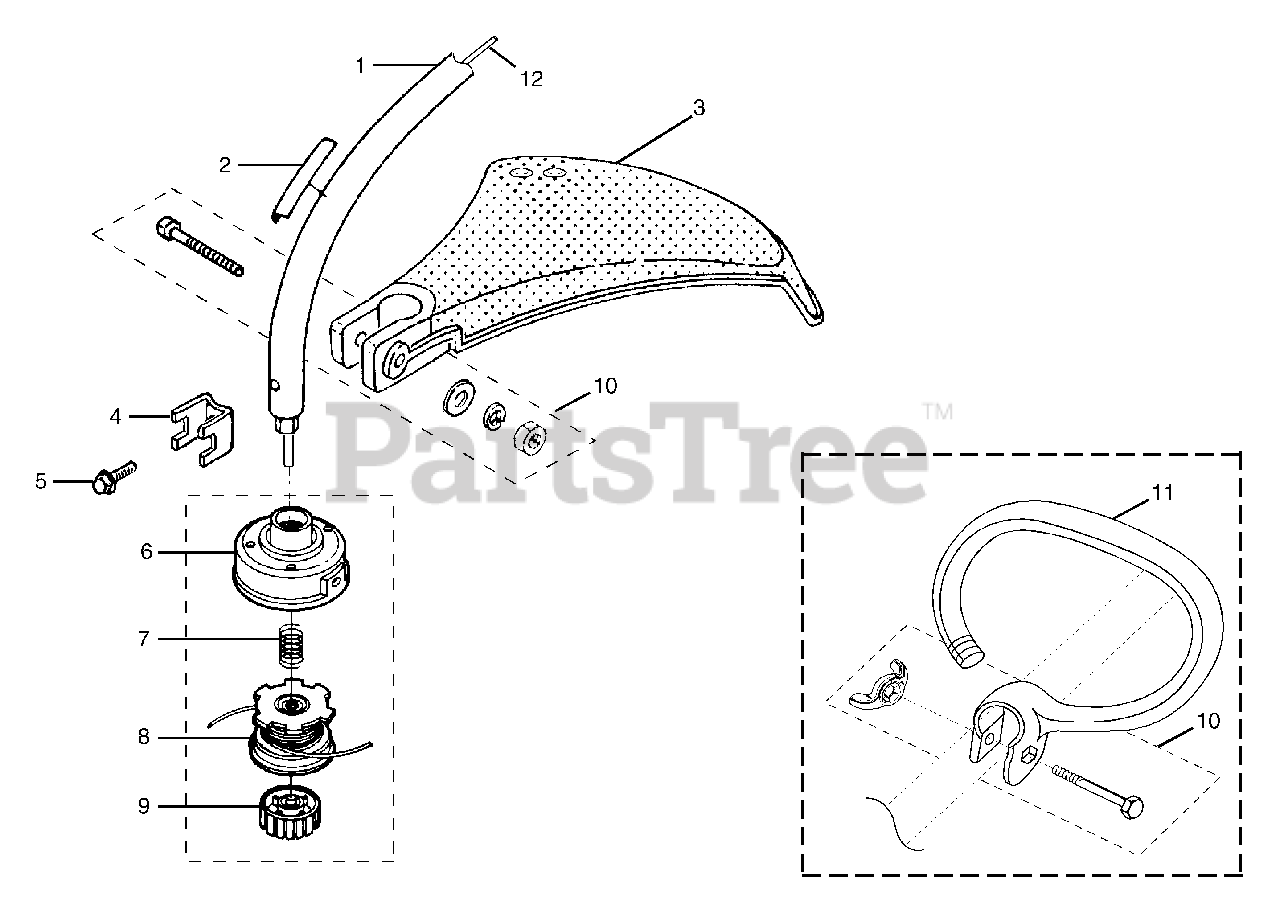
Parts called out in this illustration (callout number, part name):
1	BOOM ASSEMBLY KIT
2	BOOM DECAL (WARNING)
3	GRASS DEFLECTOR
4	CLAMP
5	SCREW
6	HOUSING AND EYELETS
7	COMPRESSION SPRING
8	SPOOL W/LINE ( 080 in )
9	SPOOL RETAINER (RH/THREAD)
10	FASTENER PARTS KIT
11	FRONT HANDLE
12	FLEX SHAFT
